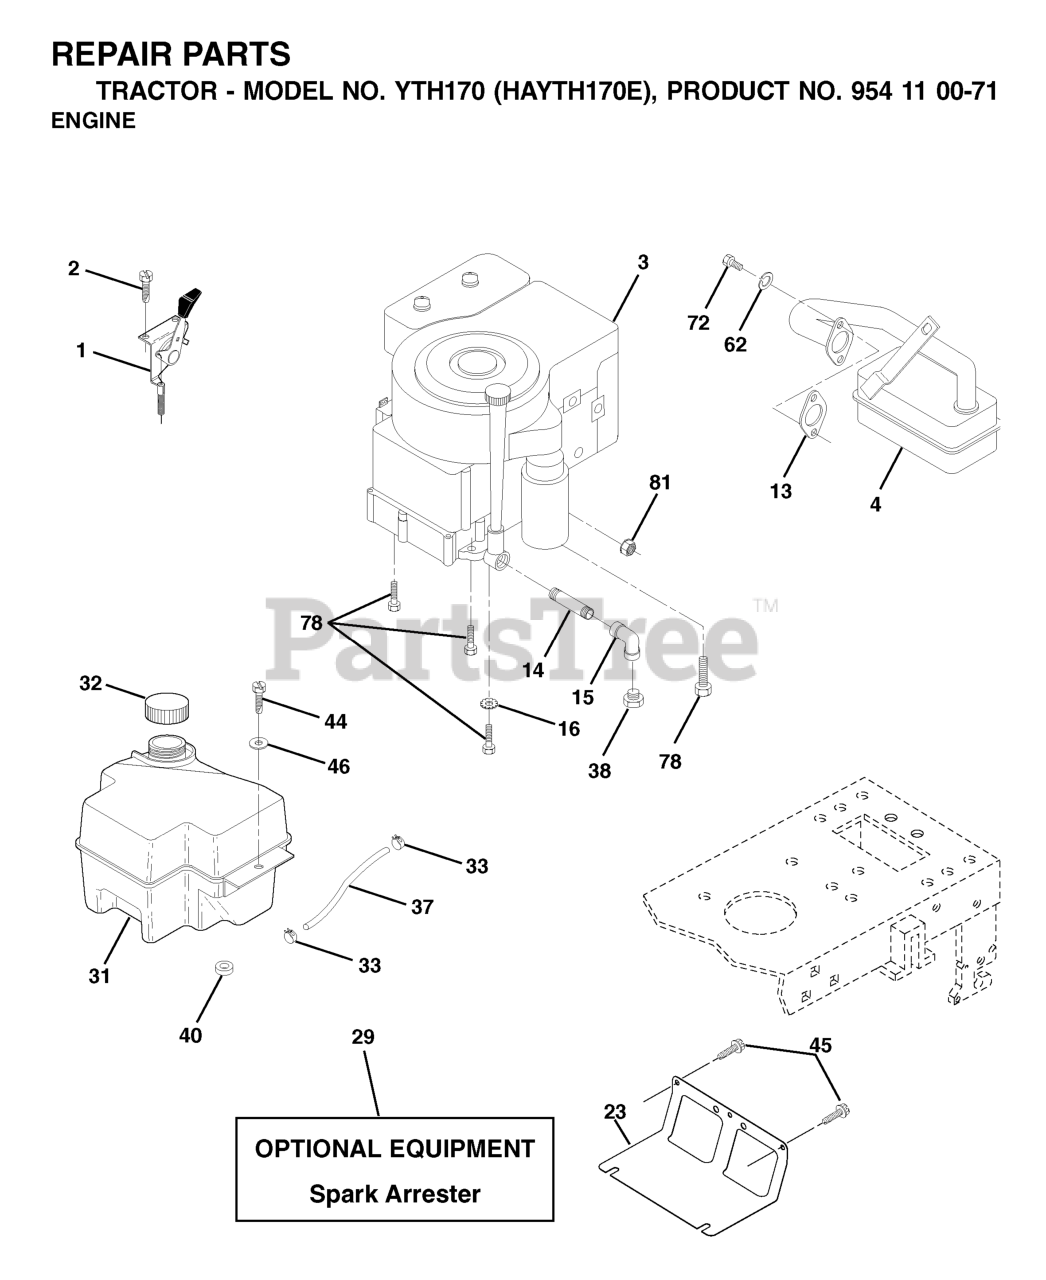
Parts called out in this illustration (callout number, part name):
1	CHOKE CONTROL
2	SCREW LT
4	MUFFLER.LT.BRIGGS.14HP.IC/OHV
13	REPL BY 532 27 22-93
14	Nipple Pipe 3/8 Npt X 3-1/2
15	ELBOW
16	LOCKWASHER
23	SHIELD.BROWNING.DBR.GUARD
29	KIT.SPARK ARRESTOR 794945 B&S
31	FUEL TANK
32	FUEL CAP
33	HOSE CLAMP
37	LINE.FUEL.20
40	BUSHING.SNAP.NYL.BLK.
44	SCREW HEXWSHR 1/4-20X3/4
45	SCREW, 3/8-16X3/4
62	WASHER.LOCK.HVY.HLCL.SPR.5/16
72	SCREW
78	SCREW.3/8-16
81	NUT
